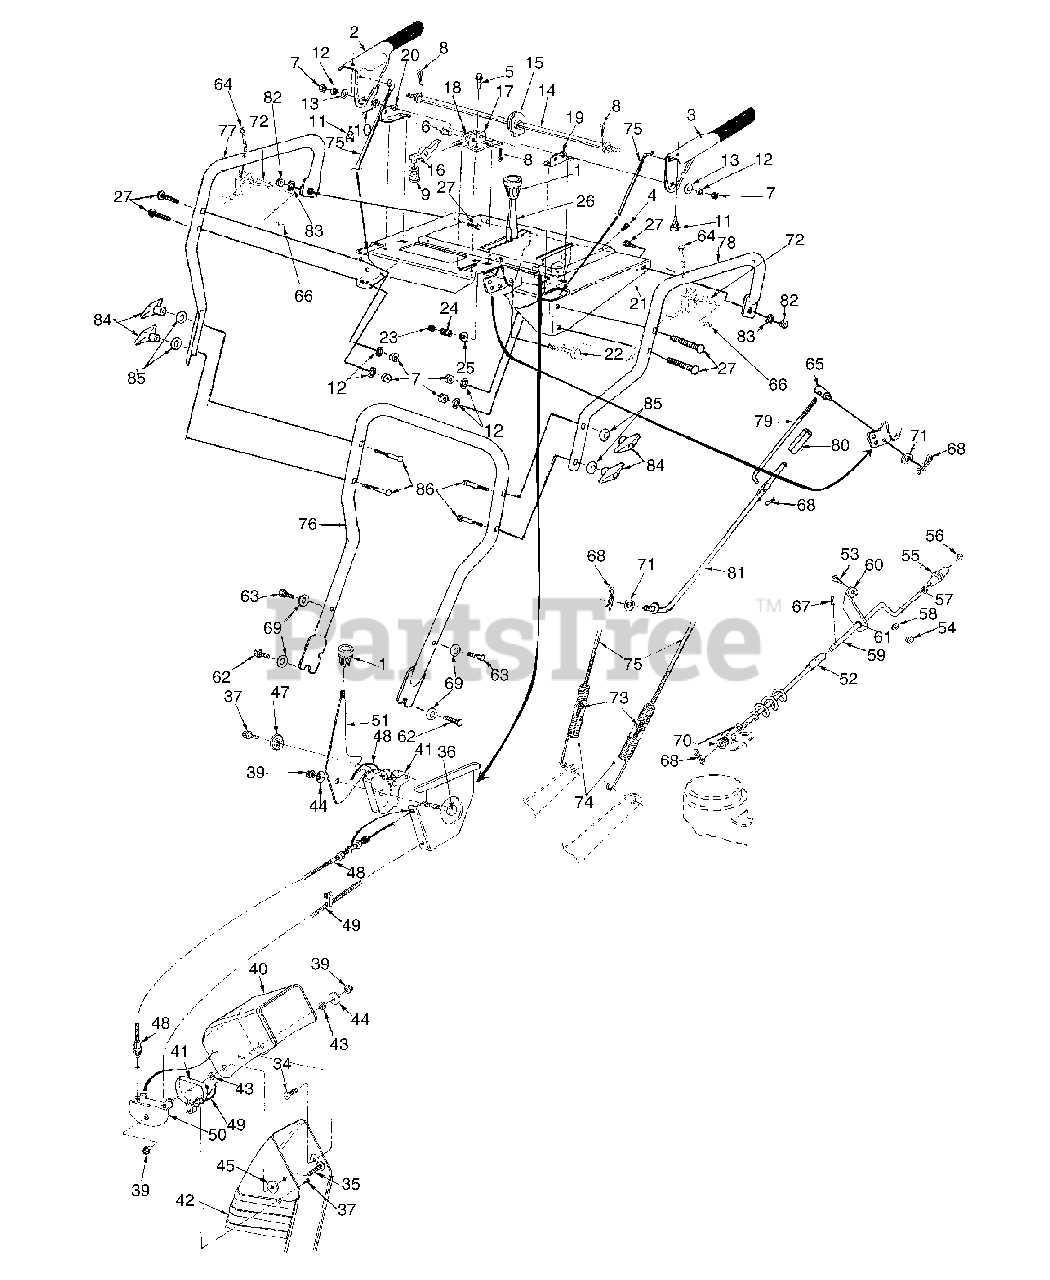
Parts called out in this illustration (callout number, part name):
1	Sml Shift Knob
2	Engage Handle RH
3	Engage Handl LH
4	Pan Head B-tapp Scr #10 x .5
5	Hwhd Sf-tap Scr 1/4-20 x 1/2 Lg.
6	Clevis Pin .31 Dia x 1.0
7	Nut Hex 5/16-18 Gd 5
8	Cot-pin 3/32 Dia x 1.0
9	Comp Spring .36 Dia x 1.0 Lg
10	Spring Torsion .44 ID
11	Rubber Bumper .63 Dia
12	Lock Washer 5/16
13	Wsher Spcl. .345 Sq. x .72 OD
14	Cam Rod
15	Clutch Lock Cam
16	Clutch Lock Pawl
22	Scr Hex Cap 3/8-24 x 1.5 Gd 5
23	Hex Ins L-nut 3/8-24
24	Compression Spring .39 ID x .88
25	Bell Wash .40 ID x .88 OD x .06
34	Carriage Bolt 5/16-18 x 1.00
35	Carriage Bolt 5/16-18 x 1.75
36	Hex Scr 5/16-18 x 1.5
37	HWHD B Tapp Scr 1/4 x 5/8 Zn
39	Hex Ins L-nut 5/16-18
40	6" Upper Chute Remote Tilt
41	Chute Tilt Cable Guide
42	6" Lower Chute Remote Tilt
43	Chute Pivot Spacer
44	Fl-wash .344 ID x .88 OD x .063
45	Flt Wshr .344 x 1.125 x .125
47	Contoured Washer
48	Chute Control Cable 66"
49	Chute Control Cable 66" W/clip
54	Hex Nut 1/4-20
55	Chute Directional Control Knob
56	Push Cap 3/8 Palnut #375011
57	Flat Washer .38 ID x .60 OD x .033
58	Bell Wash .26 ID x .75 OD x .06T
61	Plastic Bushing .380 ID
62	Hex Scr 3/8-16 x .75
63	Hex Scr 3/8-16 x 1.75
64	Scr Oval C/sunk #10-24 x 1.75
65	Adjustment Ferrule
66	#10-24 Flat Weld Nut
67	Internal Cot-pin 1/2 Dia
68	Inter Cot-pin 5/16 Dia
69	Bell Wash .4 ID x .88 OD x .06
70	Fl-wash .406 ID x .74 OD x .063
71	Fl-wash Sae .34 x .68 x .062
72	Trigger Ass'y Steer
73	Hex Ins L-nut 1/4-20
74	Extension Spring
75	Cable Clutch Drive
76	Handle Lower
79	Upper Shift Rod 5/16 x 10.57
80	2 Pc Shift Rod Connector
81	Lower Shift Rod 3/8 x 14.75
82	Hex Nut 1/4 - 20
83	Bell Wash .26 ID x .75 OD x .06T
84	Wingnut
85	Bell Wash .345 ID x .88 OD x .060
86	Carriage Bolt 5/16 -18 x 2.5
